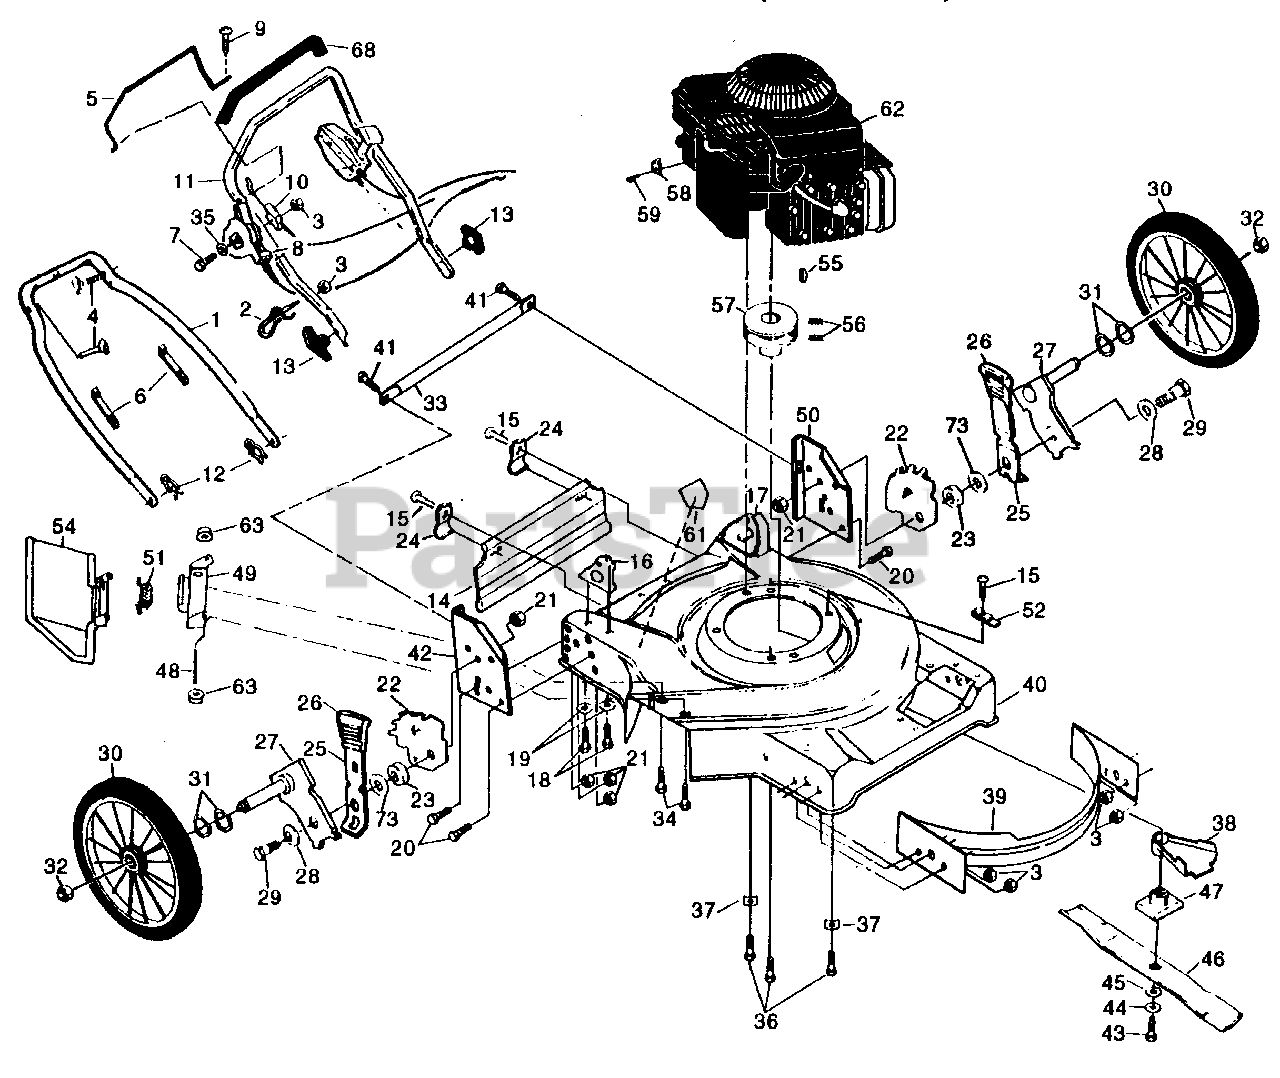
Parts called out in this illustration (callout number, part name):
1	Lower Handle (AYP part number)
2	Rope Guide
3	Locknut 1/4-20 (AYP part number)
4	Handle Bolt (AYP part number)
5	Control Bar (AYP part number)
6	Wire Tie (AYP part number)
7	Machine Screw 1/4-20 x 2-1/4 (AYP part number)
8	Throttle Control
9	Pan Head Hi/Lo Screw #10-16 x .63 (AYP part number)
10	Engine Zone Cable
11	Upper Handle (AYP part number)
12	Hairpin Cotter (AYP part number)
13	Handle Knob (AYP part number)
14	Rear Skirt (AYP part number)
15	Hex Head Screw #10 (AYP part number)
16	Handle Bracket Assembly (Right) (AYP part number)
17	Handle Bracket Assembly (Left) (AYP part number)
18	Screw 5/16-18 x 3/4 (AYP part number)
19	Washer (AYP part number)
20	Bolt, Hex Head 3/8-16 x 3/4 (AYP part number)
21	Locknut (AYP part number)
22	Wheel Adjusting Bracket (R.R.) (AYP part number)
23	Spacer (AYP part number)
24	Skirt Bracket (AYP part number)
25	Selector Spring (AYP part number)
26	Selector Knob
27	Axle Arm Assembly (AYP part number)
28	Rear Spring Washer (AYP part number)
29	Shoulder Bolt 3/8-16 (AYP part number)
30	Wheel & Tire Assembly (Rear) (AYP part number)
31	Wave Washer (AYP part number)
32	Nut (AYP part number)
33	Rod Support (AYP part number)
34	Hex Head Thread Rolling Screw w/Sems 1/4-20 x 3 (AYP part number)
35	Flat Washer (AYP part number)
36	Thread Rolling Screw 3/8-16 x 1 (AYP part number)
37	Engine Washer (AYP part number)
38	Debris Shield
39	Front Baffle (AYP part number)
40	Mower Housing Kit (Inc. 61)
41	Screw (AYP part number)
42	Wheel Support Bracket R.H. (AYP part number)
43	Hex Head Screw 3/8-24 x 1-3/8 Gr. 8
44	Helical Washer 3/8 (AYP part number)
45	Hardened Washer (AYP part number)
46	22" Blade
47	Blade Adapter
48	Hinge Rod (AYP part number)
49	Housing Bracket (AYP part number)
50	Wheel Support Bracket L.H. (AYP part number)
51	Torsion Spring (AYP part number)
52	Guide Clip (AYP part number)
54	Discharge Guard
55	Hi-Pro Key (AYP part number)
56	Set Screw (AYP part number)
57	Engine Pulley (AYP part number)
58	Cable Clamp (AYP part number)
59	Screw #10 x 5/8 (AYP part number)
61	Danger Decal (AYP part number)
63	Push Nut (AYP part number)
68	Handle Grip (AYP part number)
73	Flat Washer 3/8 (AYP part number)
